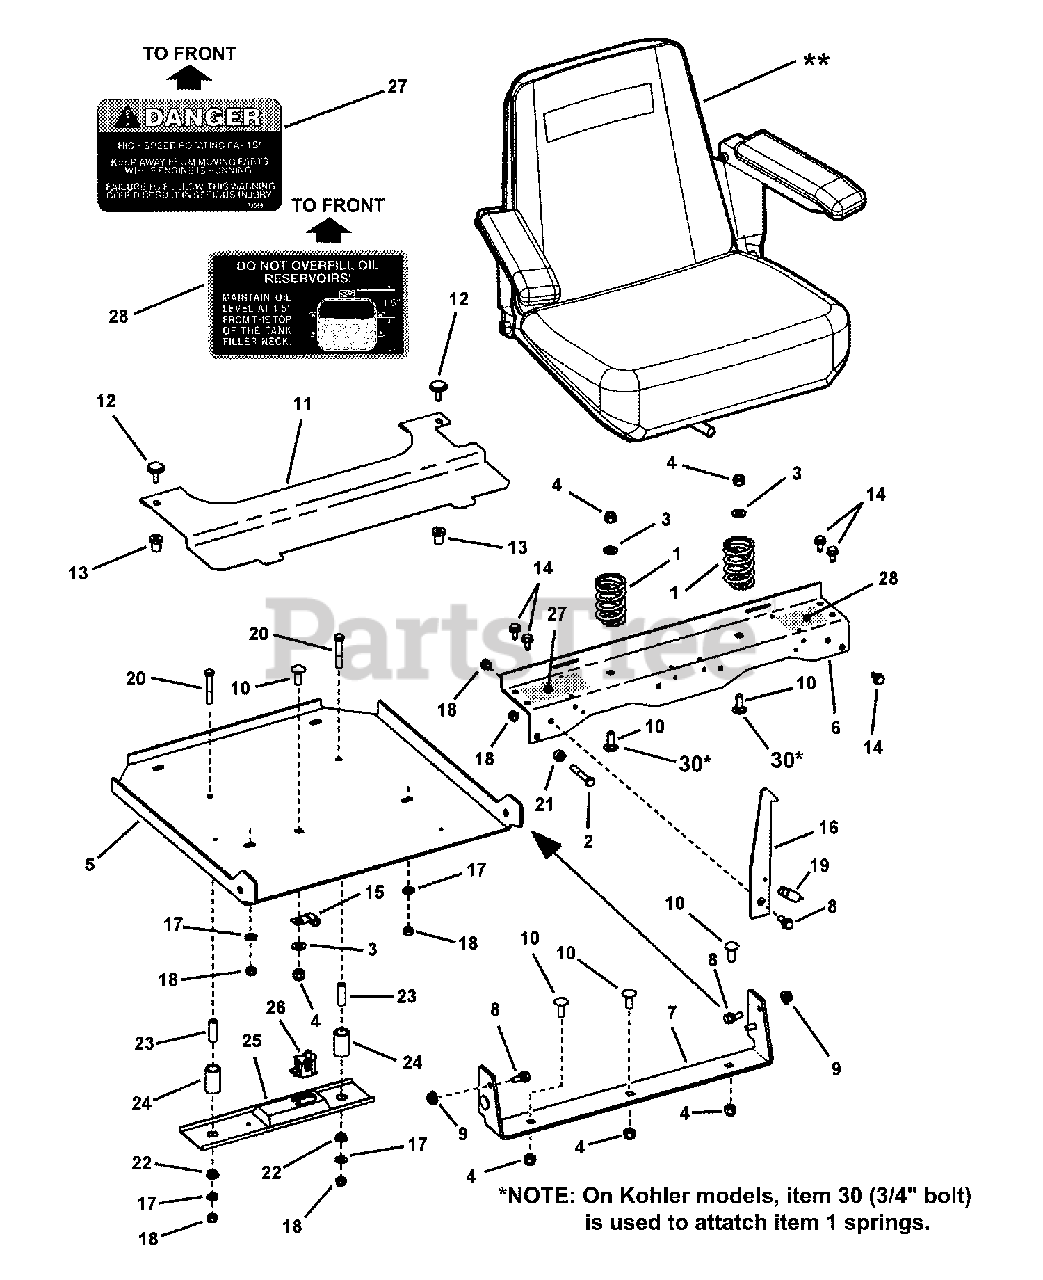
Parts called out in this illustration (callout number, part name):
1	SPRING, Compression- Seat Support 2.75" Tall
1	SPRING, Compression- Seat Support 2.25" Tall
2	SCREW, 5/16-18 x 3/4" Hex Washer Self-Tap
3	WASHER, 3/8" SAE Flat
4	NUT, 3/8-16 HEX NYLON LOCK
5	SEAT PAN
6	CROSSMEMBER, Seat Support
7	WELDMENT, Hinge Bracket (shown)
8	SHOULDER BOLT, 5/16-18
9	NUT, 5/16-18 Large Flange Hex Center Lock
10	BOLT, 3/8-16 x 1" Square Neck Carriage GR 5
11	GUARD, Fan
12	KNOB, 1/4-20 x 3/4" Thread
13	WELL-NUT, 1/4-20 x 53/64
14	SCREW, 5/16-18 x 5/8" Hex Washer Self-Tap
15	CLIP, Open 3/8" Cushioned
16	LATCH, Seat Support
17	WASHER, 5/16" Flat
18	NUT, 5/16-18 HEX NYLON LOCK
19	SPRING, Extension
20	BOLT, 5/16-18 X 2", GD5
21	SPACER, .340 I.D. x .63 O.D. x .310 Thick
22	BUSHING, Seat
23	SPACER
24	SPRING, Compression 1.52" Tall
24	SPRING, Compression 1.72" Tall
25	HOLDER, Seat Switch
26	SWITCH, Seat, NC
27	DECAL, Danger- High Speed Rotating Parts
28	DECAL, Reservoir Oil Level
30	BOLT, 3/8-16 x 3/4" Square Neck Carriage
